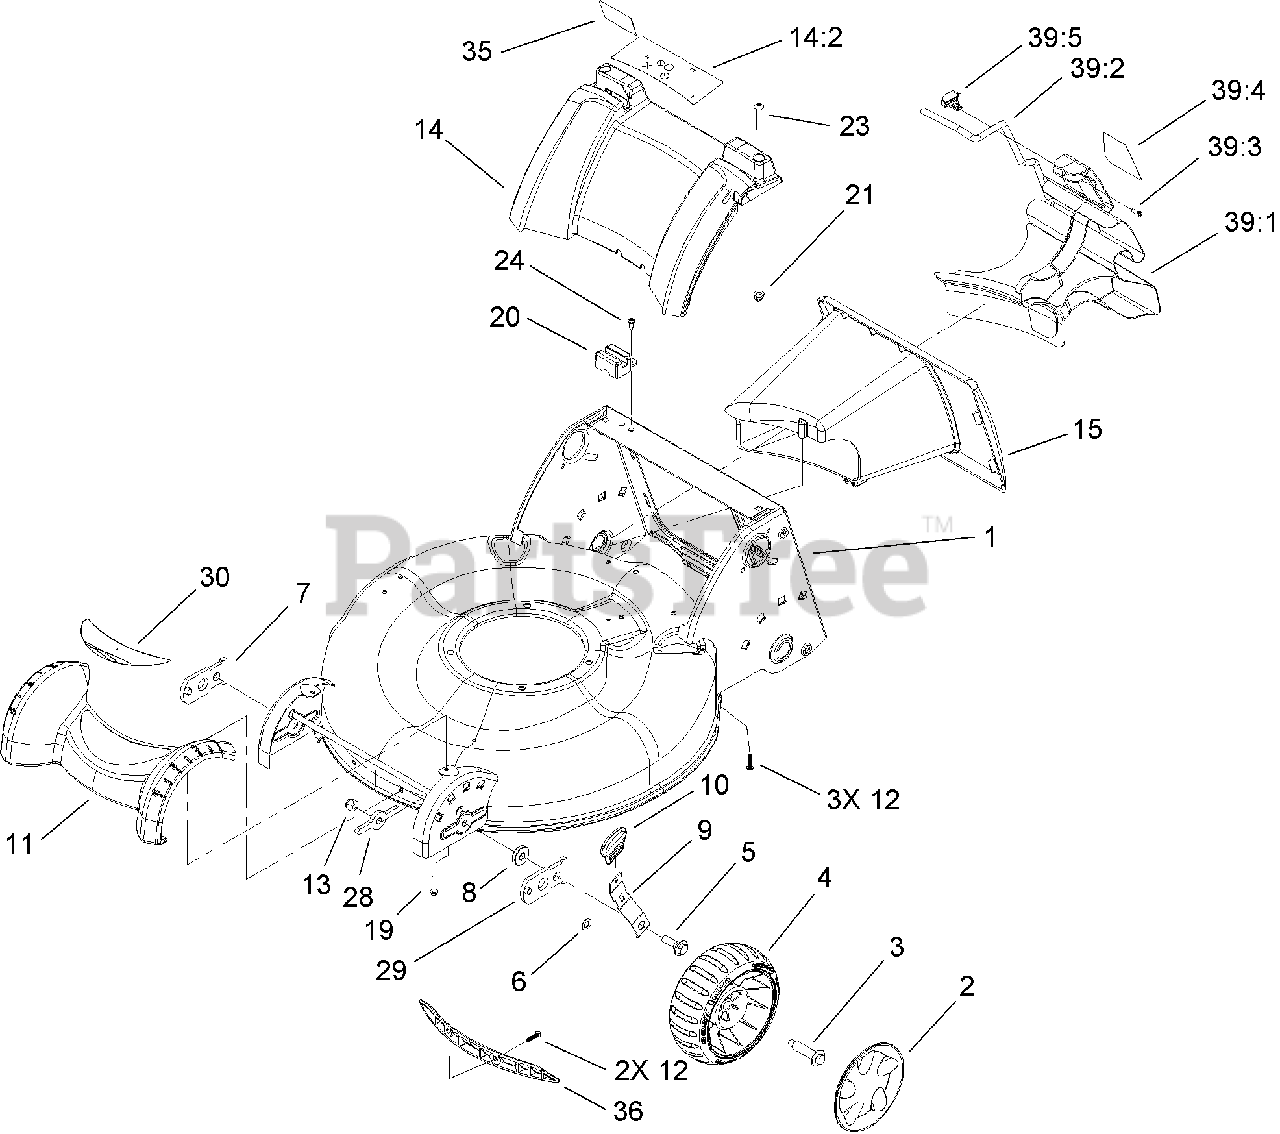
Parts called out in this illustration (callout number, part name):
1	HOUSING ASM
2	COVER-WHEEL, 7 INCH
3	BOLT-SHOULDER
4	7 INCH WHEEL ASM
5	BOLT-SHOULDER
7	ARM-PIVOT, RH
9	ARM-SPRING
10	KNOB-LEVER, HOC
11	COVER-FRONT
12	SCREW-PLASTITE
13	NUT-LOCK, NI
14	COVER-REAR
14:2	DECAL-WARNING
15	TUNNEL
19	SCREW-PLASTITE
20	MODULE-SWITCH
21	NUT-CLIP
23	SCREW-PTH
24	SCREW-THREAD FORMING
28	WASHER-SUPPORT, FRONT
29	ARM-PIVOT, LH
35	DECAL-BAG ATTACHMENT, CE
36	INSERT-HOUSING
39:1	PLUG-CHUTE
39:2	LATCH-PLUG
39:3	SCREW-PPH
39:4	DECAL-MULCH PLUG, CE
39:5	RETAINER-LATCH
